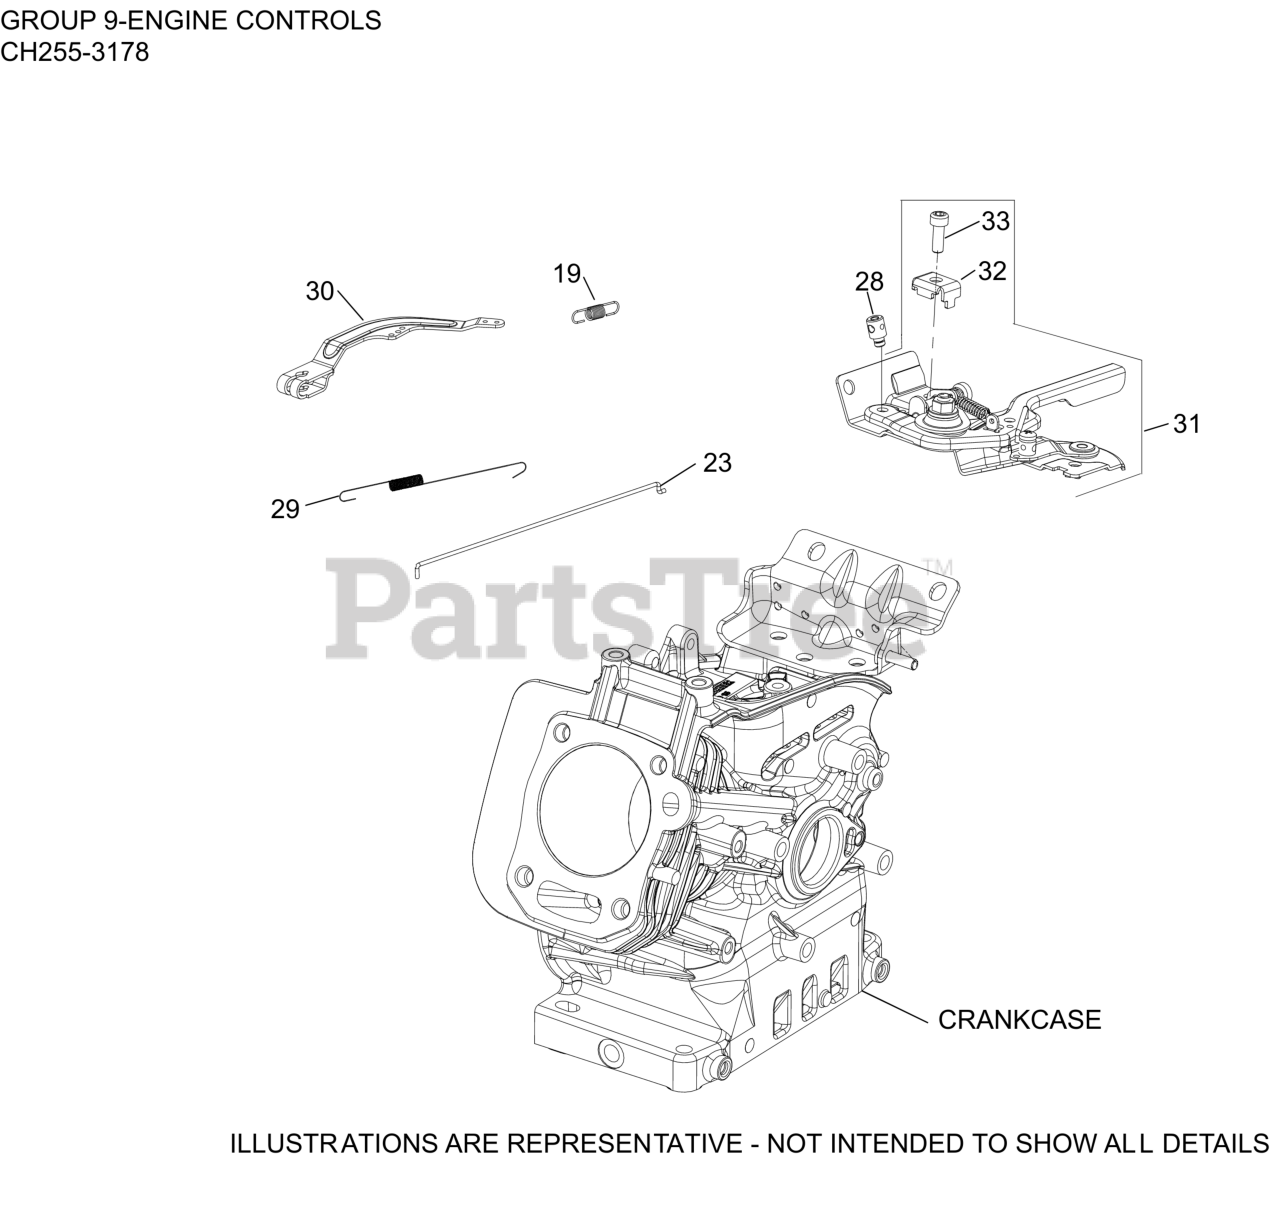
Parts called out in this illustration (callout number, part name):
19	SPRING, GOVERNOR
23	LINKAGE, GOVERNOR-USE 18 079 05-S
28	KIT, CABLE CLAMP
29	SPRING, LINKAGE
30	KIT, GOVERNOR LEVER
31	VARIABLE SPEED CONTROL ASSEMBLY
32	CLAMP, CABLE
